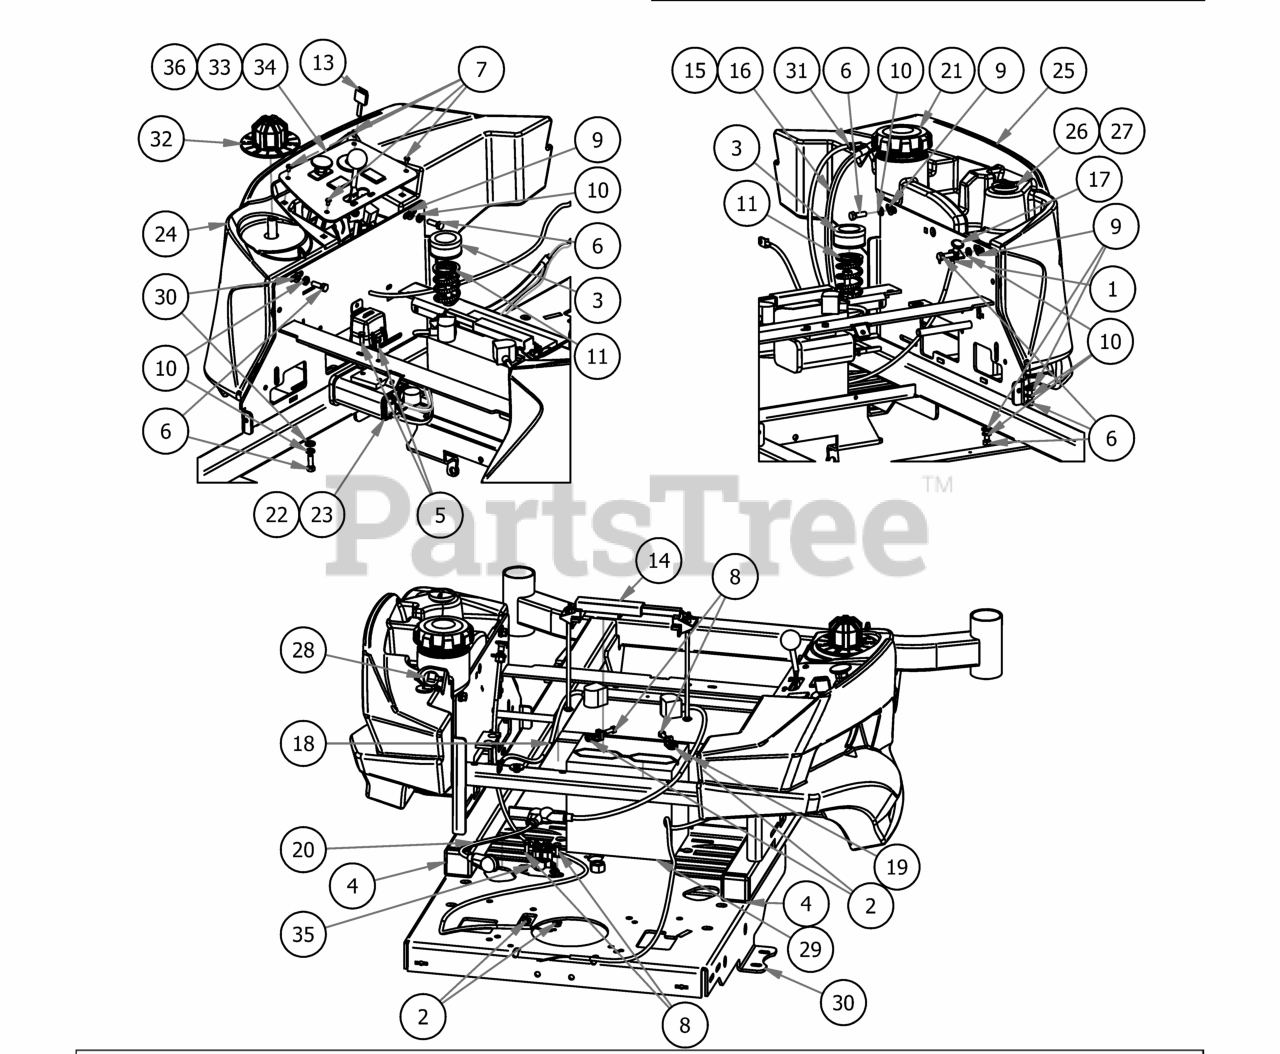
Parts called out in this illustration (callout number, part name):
1	3/8" Fine Threaded Jam Nut
2	1/4-20 Hex Flange Nuts Zinc w/Serrations
3	Seat Spring Cap Cover
4	2X2 Frame Plug
5	M6-1.0 X 16MM Hex Bolt
6	5/16" x 1" Bolt
7	10-32 x 3/8" Button Socket Head Bolt
8	1/4" x 3/4" Hex Bolt
9	5/16" Flat Washer
10	5/16" Lock Washer
11	Seat Spring Assembly
13	Ignition Key
14	Hold Down Assembly
15	15" Fuel Line Assembly (Kawasaki Engine)
16	37" Fuel Line Assembly (Kohler Engine)
18	Ground Cable
19	24" Red Battery Cable
20	12" Red Battery Cable
21	Tethered Fuel Tank Cap
22	MZ Kohler EPA Canister Assembly (Kohler KS-590 Only)
23	MZ Kohler EPA Canister Assembly
24	2017 MZ Right Gas Tank
25	2017 MZ Left Gas Tank
26	Fuel Gauge
27	Fuel Gauge Grommet
28	Rollover Valve
30	2017 MZ/ZT 42"-48" Frame
31	3/16 Vinyl Clamp
32	MZ/ZT Deck Height Dial
33	2017 Magnum Control Panel Assembly
34	2017 MZ Control Panel Assembly
36	Tach Wire (Only used with Magnum Control Panel)
